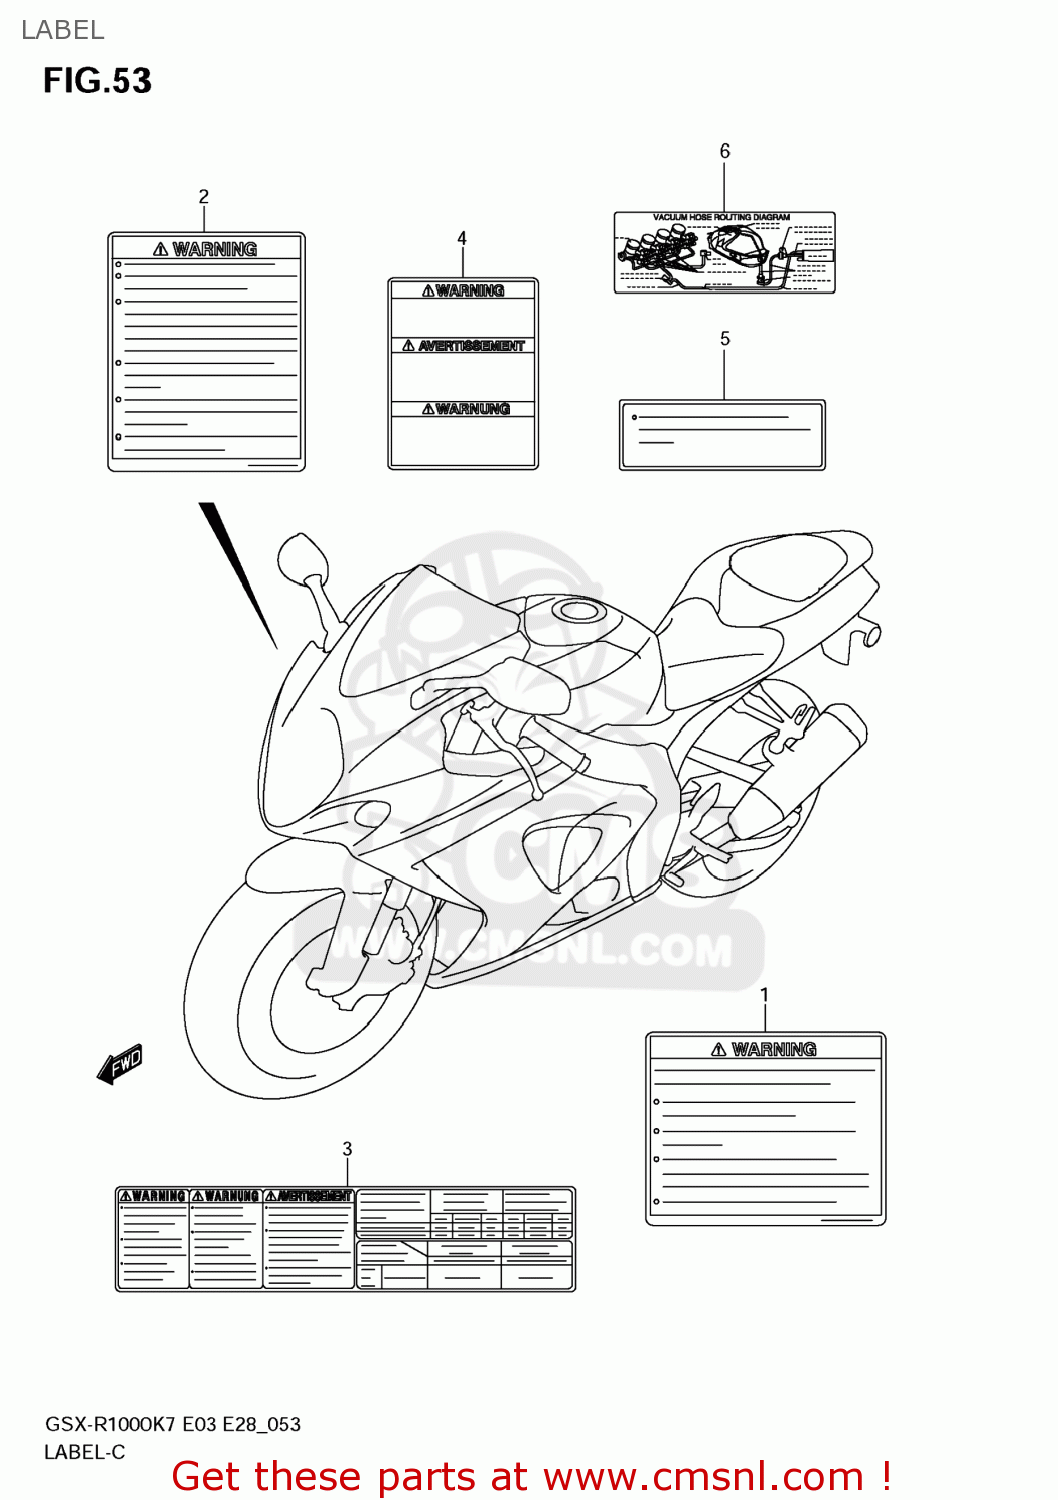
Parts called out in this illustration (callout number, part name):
1	LABEL,GENERAL WARNING
2	LABEL,SCREEN
3	LABEL,TIRE INFORMATION
4	LABEL,WARNING STEERING
5	LABEL,MANUAL NOTICE
6	LABEL,VACUUM HOSE ROUTING
7	MANUAL,OWNER'S
